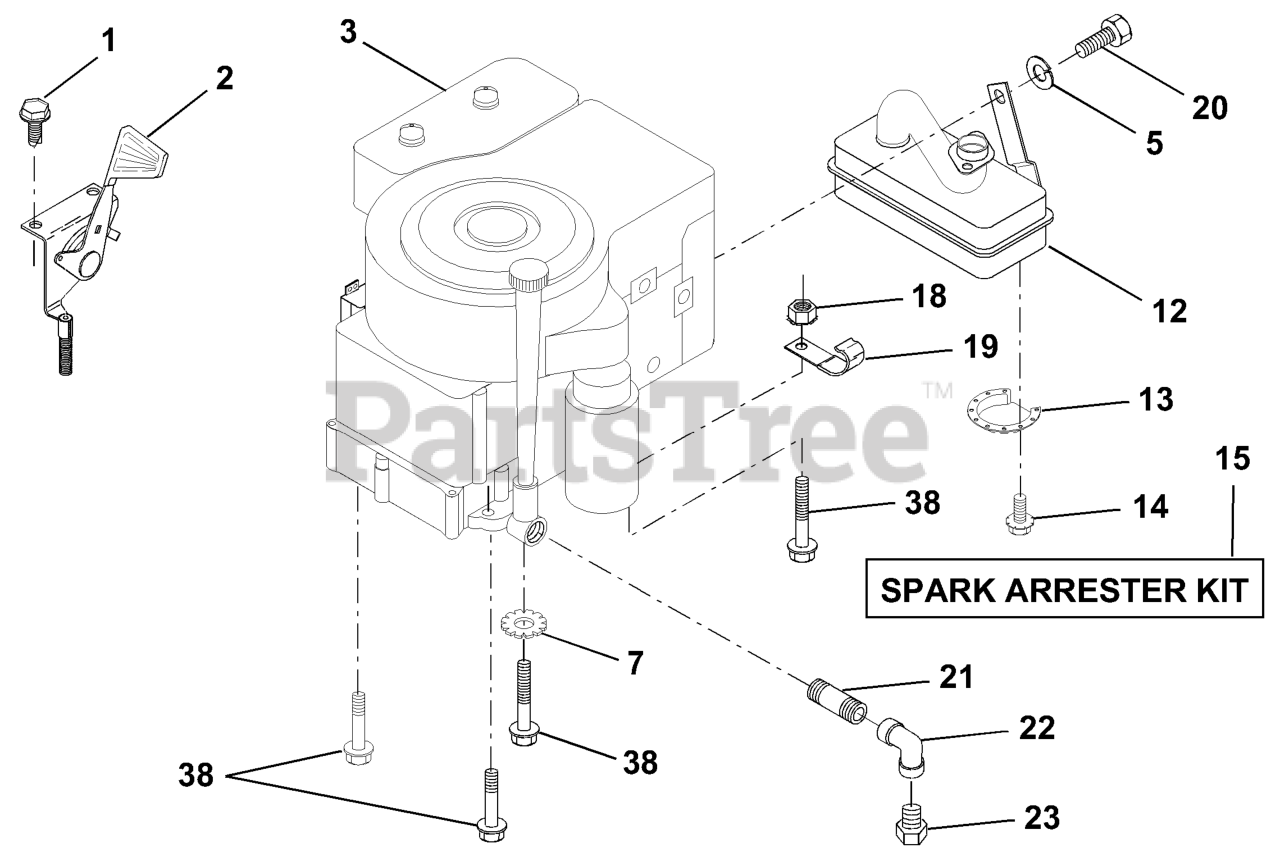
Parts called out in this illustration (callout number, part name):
2	THROTTLE CONTROL
3	Engine, Kohler, 12.5 HP
5	WASHER.LOCK.HVY.HLCL.SPR.5/16
7	LOCKWASHER
12	MUFFLER KOH
13	DEFLECTOR, MUFFLER
14	SCREW
15	KIT.SPARK ARRESTOR 794945 B&S
19	CLIP T
20	Bolt, Hex, Fin. 5/16 - 18 x 1/2
21	Nipple Pipe
22	ELBOW
23	Oil Drain Plug
38	BOLT, HEX
